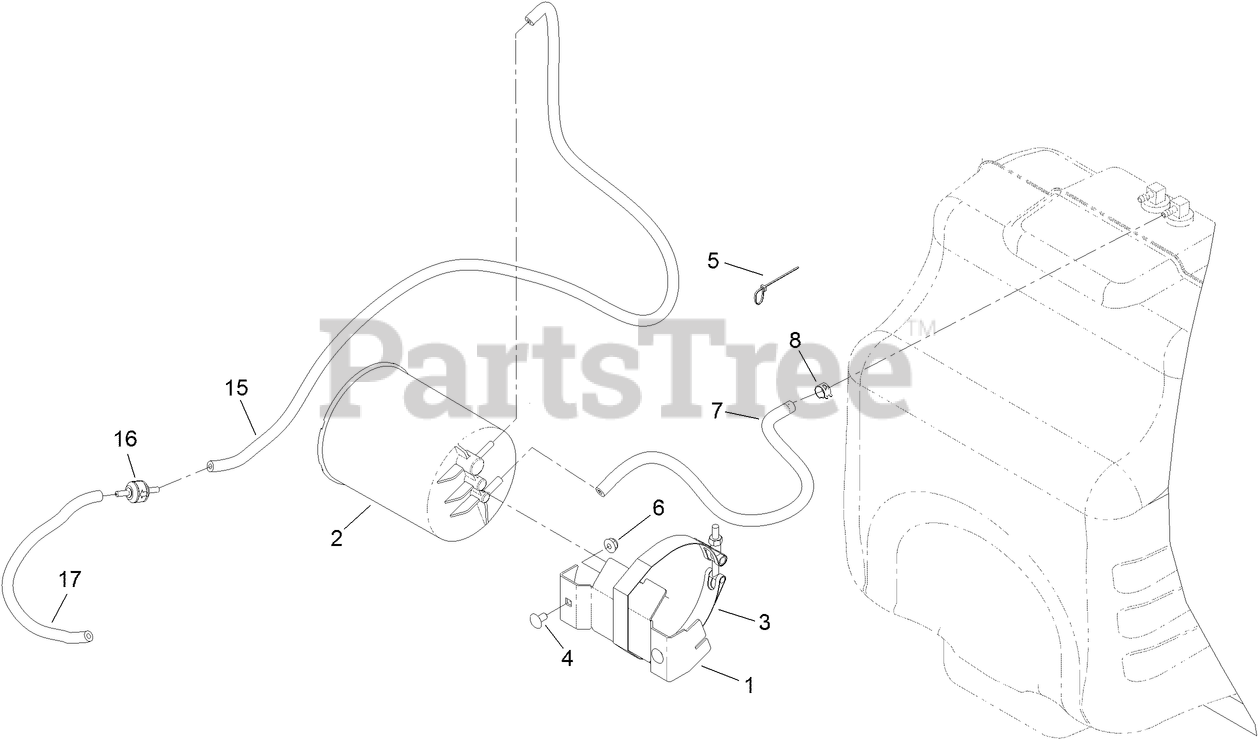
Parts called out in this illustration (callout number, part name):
1	BRACKET-CANISTER
2	CANISTER-CARBON, 1200CC
3	CLAMP-T-BOLT
4	SCREW-CARR
5	TIE-CABLE
6	NUT-HF
7	HOSE-FUEL
8	CLAMP-HOSE
15	HOSE-EMISSIONS
16	VALVE-CHECK, VACUUM
17	HOSE-VENT, FORMED
